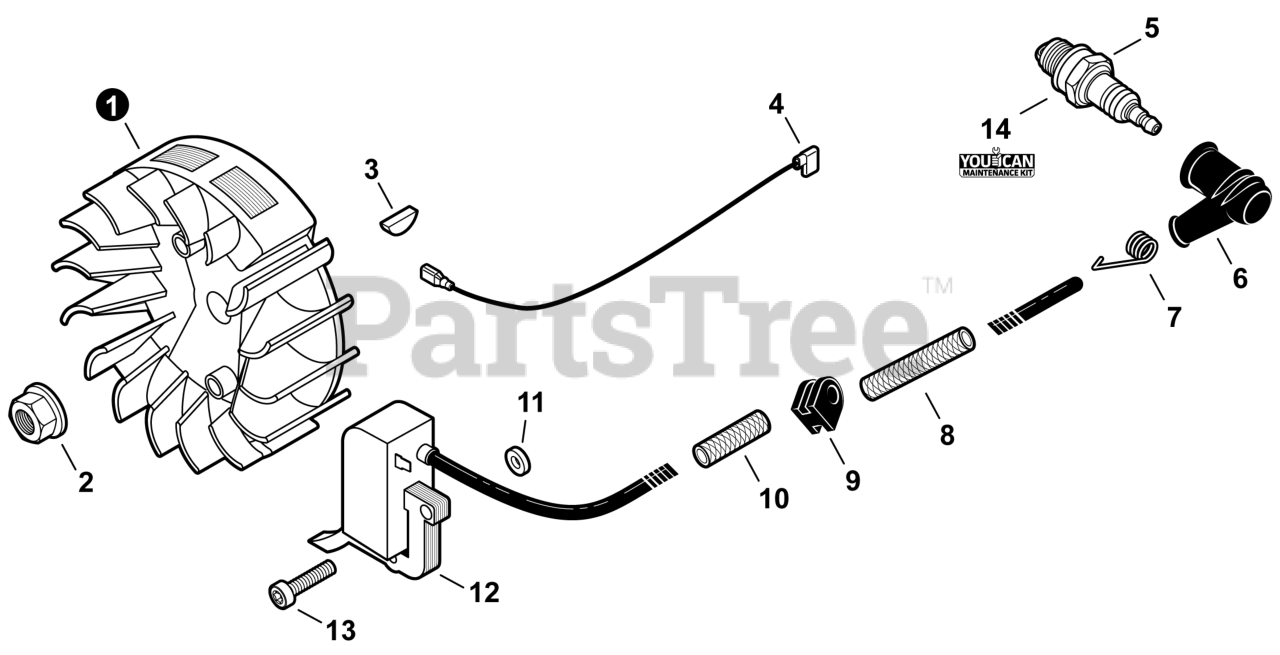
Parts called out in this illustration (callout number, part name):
1	FLYWHEEL
2	NUT, FLANGE M8
3	KEY, WOODRUFF
4	LEAD - IGNITION
5	SPARK PLUG - BPM8Y
6	CAP, SPARK PLUG
7	TERMINAL, SPARK PLUG
8	TUBE, INSULATOR 7×8.6×40
10	TUBE, INSULATOR 7×8.6×30
11	WASHER 5.2×12×3
12	COIL, IGNITION
13	BOLT, TORX 5×20
14	TUNE-UP KIT - YOUCANT
